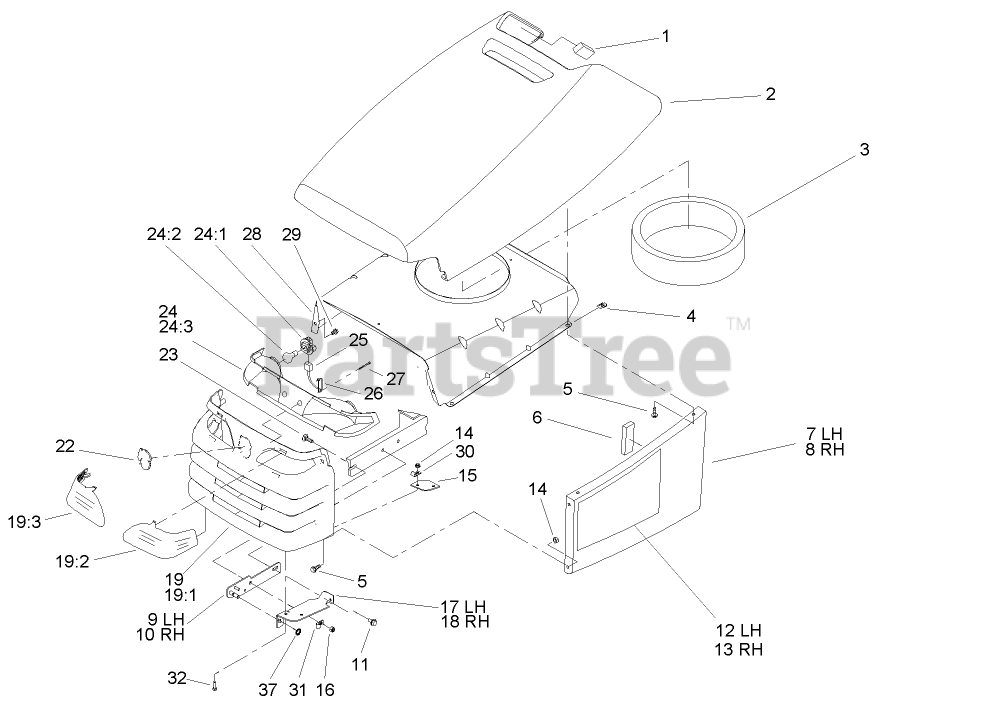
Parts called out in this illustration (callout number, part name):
1	FOAM-HOOD
3	SEAL-AIR INLET, TWIN
5	SCREW-HWH
6	FOAM-SIDEPANEL
7	HOOD-SIDE, LH
8	HOOD-SIDE, RH
9	BRACKET-HINGE, LH
11	SCREW-HWHTF
12	DECAL-HOOD, LH
14	NUT-LOCK, HHF
16	NUT-LOCK, NI
17	BRACKET-HOOD, HINGE, LH
19:1	GRILLE
19:2	LENS-LH
19:3	LENS-RH
22	EMBLEM
23	SCREW-CARR
24:1	SOCKET-HEADLIGHT
24:2	BULB
24:3	REFLECTOR
25	HARNESS-WIRE, HEADLIGHTS
26	TIE-CABLE
27	SCREW
28	BAFFLE-HOOD, UPPER
29	SCREW-PLASTITE
30	CLAMP-R
31	CLAMP-R
32	SCREW-HH
37	O-RING
